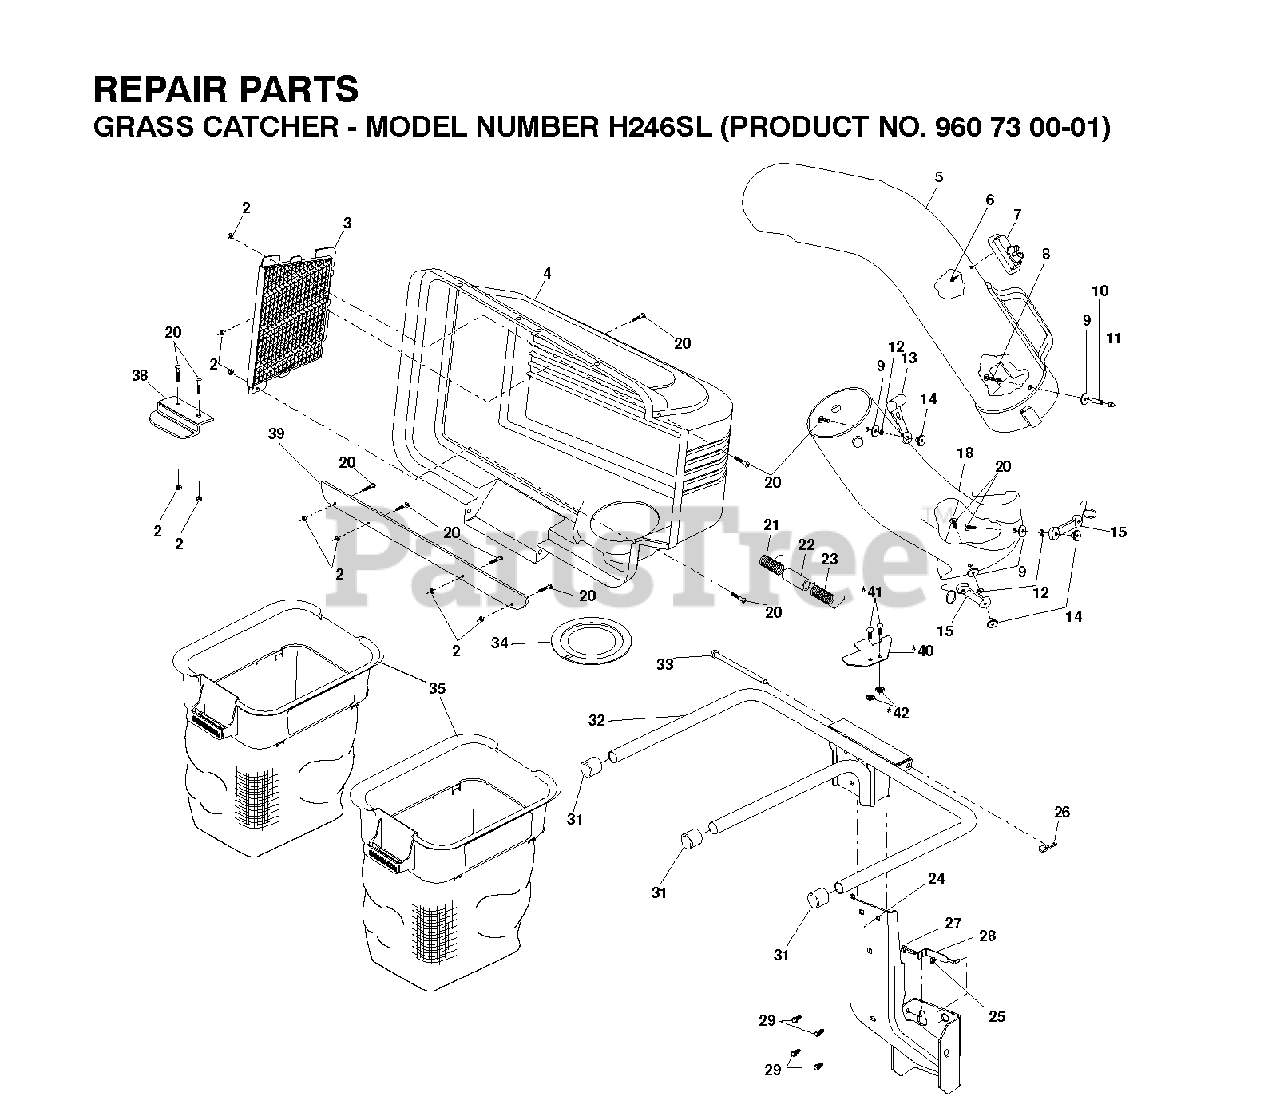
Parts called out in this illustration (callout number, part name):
2	LOCKNUT
3	COVER SCREEN
4	COVER.ASM.BAG.W/STRIP
5	CHUTE.UPPER.46"
7	INDICATOR ASM BAG
8	SCREW
9	RP STEEL WASHER
10	Spacer, Lt
11	NUT
12	LOCKWASHER
13	LATCH.HOOD.
14	WELDNUT
15	LATCH ASSY
18	CHUTE.LOWER.LT.46"
20	SCREW
21	SPRING COVER LH
22	SPACER.COVER.BAGGER
23	SPRING COVER RH
24	Bagger Support Post, Black
25	LOCKNUT.NYLOC.1/4-20
26	RETAINER-SPRNG RB
28	STOP BRACKET, BAGGER 2 BIN
29	SHOULDER BOLT 5/16-18TT
31	PLUG, TUBING END
32	FRAME.ASM.BAGGER.2BIN.QC42B
33	BAGGER.HINGE.PIN
34	GASKET.COVER.BAGGER
35	CONTAINER BAG, SOFT
38	LATCH CER38
39	STRIP.REINFORCE.BAGGER.2BIN.BL
